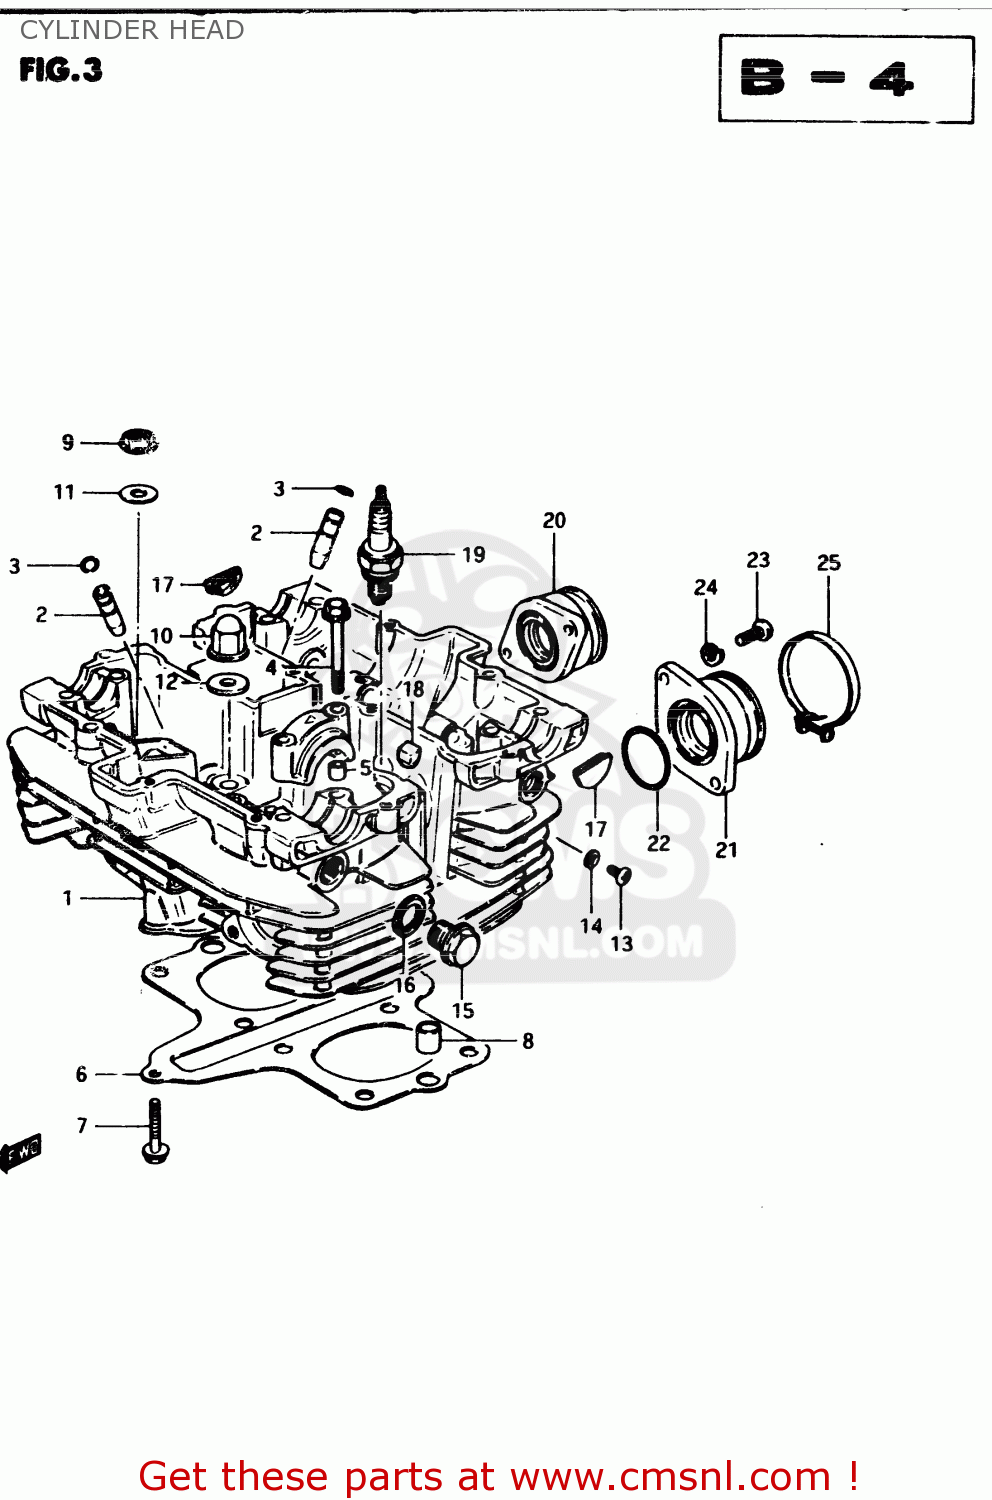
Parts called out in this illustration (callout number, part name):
1	HEAD ASSEMBLY,CYLINDER
2	GUIDE,INTAKE VALVE
3	RING,SNAP
4	BOLT(6X39)
5	PIN(6.2X8X11)
6	GASKET,CYLINDER HEAD (MCA)
7	BOLT
8	PIN
9	NUT
10	NUT
11	WASHER(8.5X19X2.3)
12	GASKET(8.5X20X2.3) (NAS)
13	SCREW
14	GASKET(5.3X9.3X1.2) (NAS)
15	PLUG (14X12)
16	GASKET(14X19.2X2) (NAS)
17	PLUG
18	PAD,CYLINDER HEAD
19	SPARK PLUG D9EA
20	PIPE,INTAKE,R
21	PIPE,INTAKE,L
22	O-RING (D:2.4 ID:29.7)
23	SCREW
24	LOCK WASHER
25	CLAMP
